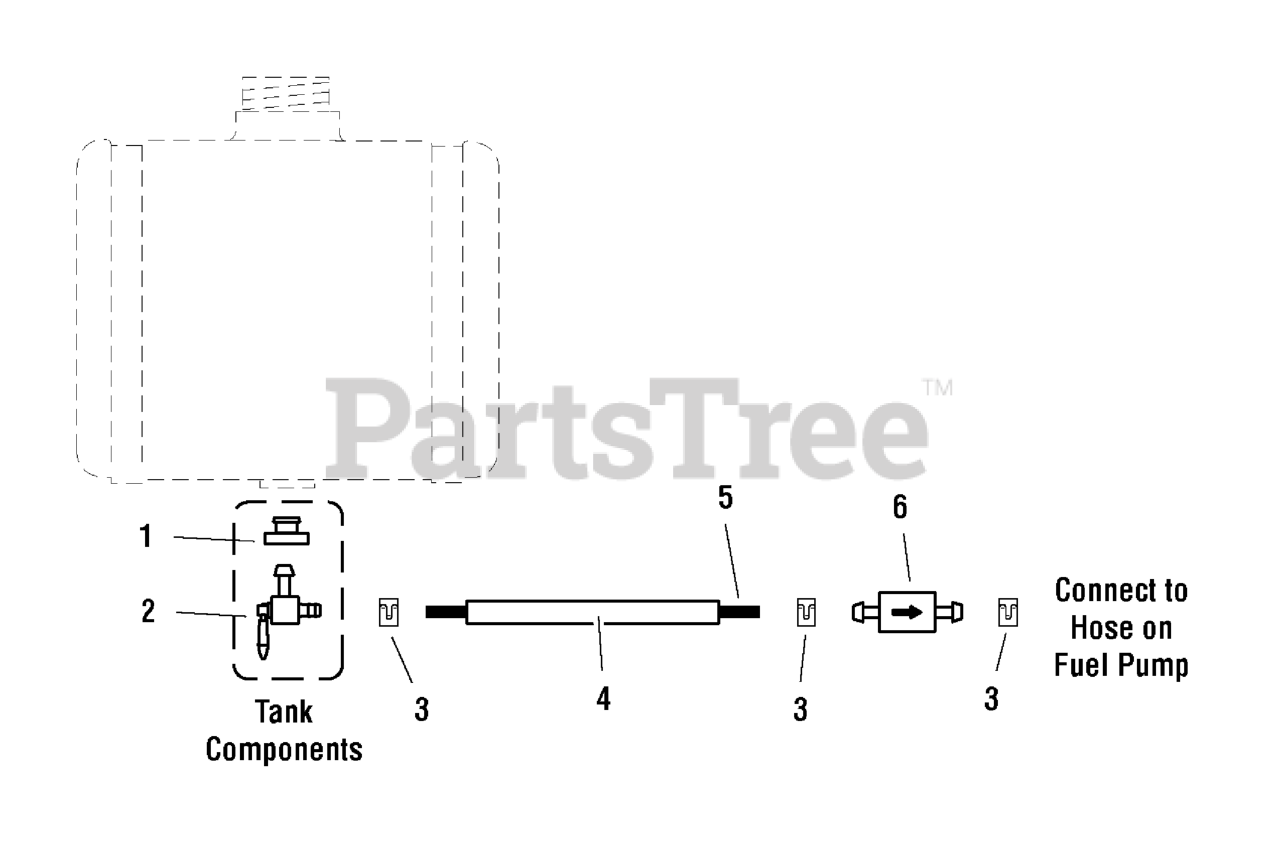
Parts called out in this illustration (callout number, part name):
1	BUSHING-FUEL TANK RED RUBBER
2	FUEL SHUTOFF VALVE
3	CLAMP, Hose
4	WIRE LOOM, 20"
5	HOSE, 1/4" FUEL, 21.00"
6	FUEL FILTER
